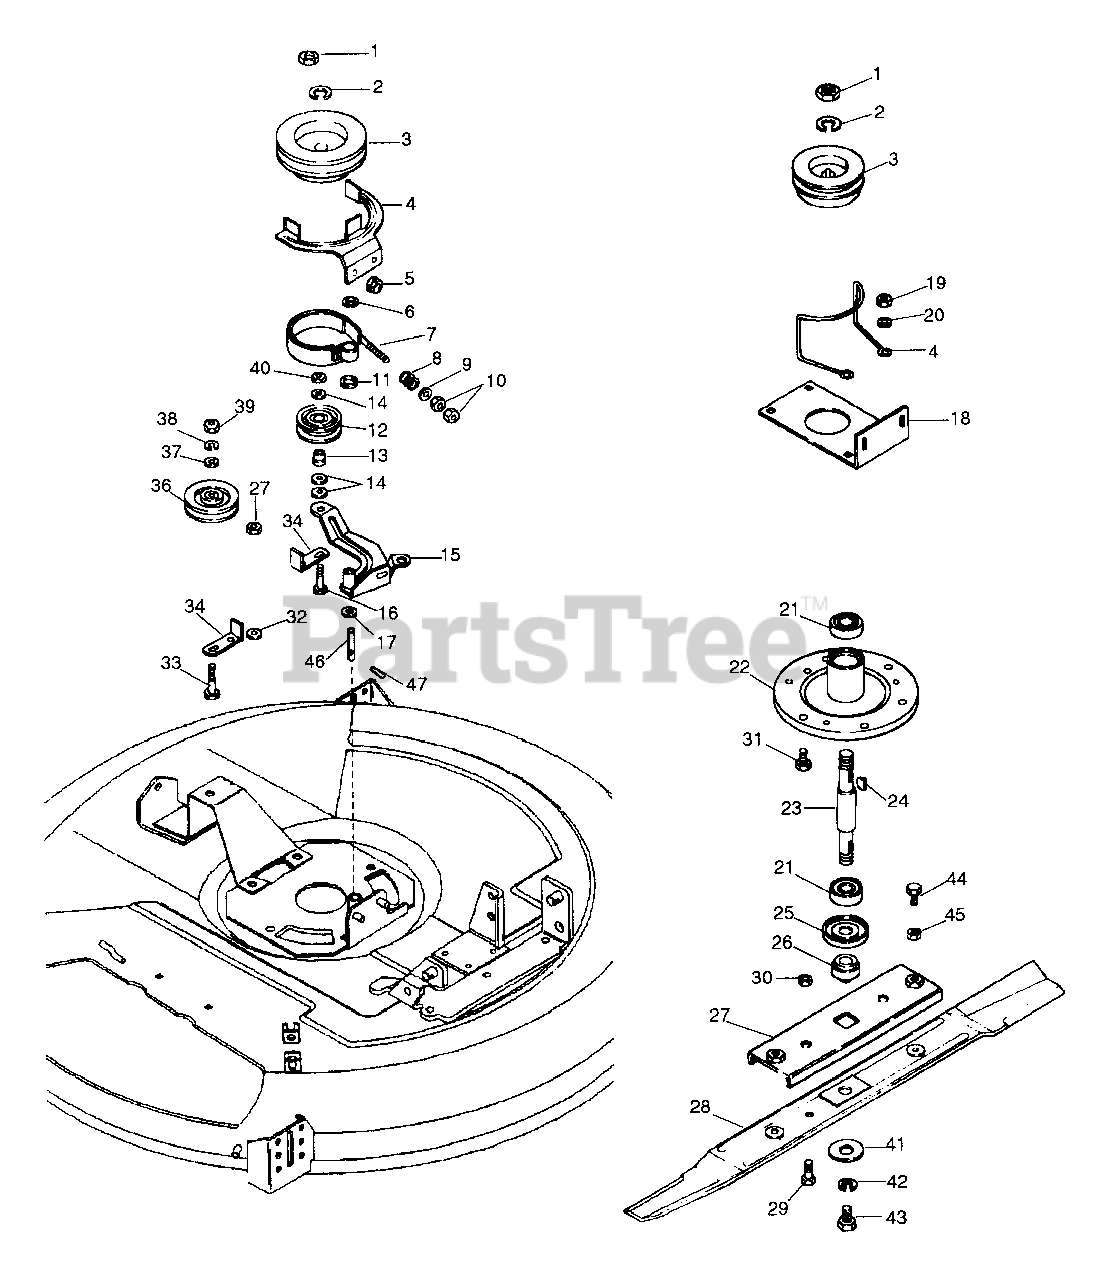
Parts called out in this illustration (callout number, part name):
1	NUT-JAM .75-16 PL
2	WSHR-LK .750X.188 MED PL
3	MOWER SHEAVE
3	MOVER SHEAVE
3	MOWER SHEAVE 28"
4	MOWER BELT FINGER
4	BELT FINGER
5	NUT-FLG. .312-18 PL
6	FASTENER
7	BRAKE BAND
8	SG-COMP .072X.687X.75
9	WSHR-FL-STL.344X.688X.065PL
10	NUT-HEX .312-18
11	WSHR-FL-STL .640X1.005X.062 PL
12	IDLER
13	SPCR, BRG .315X.50X.688X.281
14	WSHR-FL-STL .38X.875X.083 PL
15	IDLER ARM
16	BLT-HEX .31-18X1.50 PL GR2
17	WSHR-FL-STL .382X.812X.062
18	PLATE
19	NUT-LK-CTR .375-16 GR A PL
20	WSHR-FL-STL .406X.865X.094 PL
21	BRG-BALL .750X1.781X.61
22	SPINDLE HOUSING
23	SPINDLE SHAFT
24	KEY-WDRF .188X.75X.313 SAE 9
25	BEARING SLINGER
26	RETAINER HUB
26	HUB
27	BLADE TRAY
27	BLADE TRAY WELDMT
28	28" MOWER BLADE
28	MOWER BLADE 30 INCHES
28	32" BLADE
28	BLADE 28"
29	BLT-HEX .38-16X1.00 PL GR5
30	NUT-LK TOP .375-16 GR C YWZC
31	BLT-HEX .38-16X1.00 PL
32	WSHR-FL-STL.406X.812X.065PL
32	WSHR-FL-STL .406X1.000X.188 PL
33	BLT-HEX .38-16X1.75 PL GR2
34	BELT FINGER
36	IDLER-V 3.06 X .38
37	WSHR-FL-STL .390X.750X.125 PL
38	WSHR-LK .375X.094 MED PL
39	NUT-HEX .375-16
40	NUT-LK .312-18 GR A PL
41	WSHR-FL-STL .505X1.140X.250
41	WSHR-LK .438X.133 HVY
43	BLT-HEX .44-20X1.75 PL GR5
44	BLT-HEX .38-24X1.25 PL GR5
45	NUT JAM .375-24 PL
46	PIN
47	PIN-ROLL .125X.63
